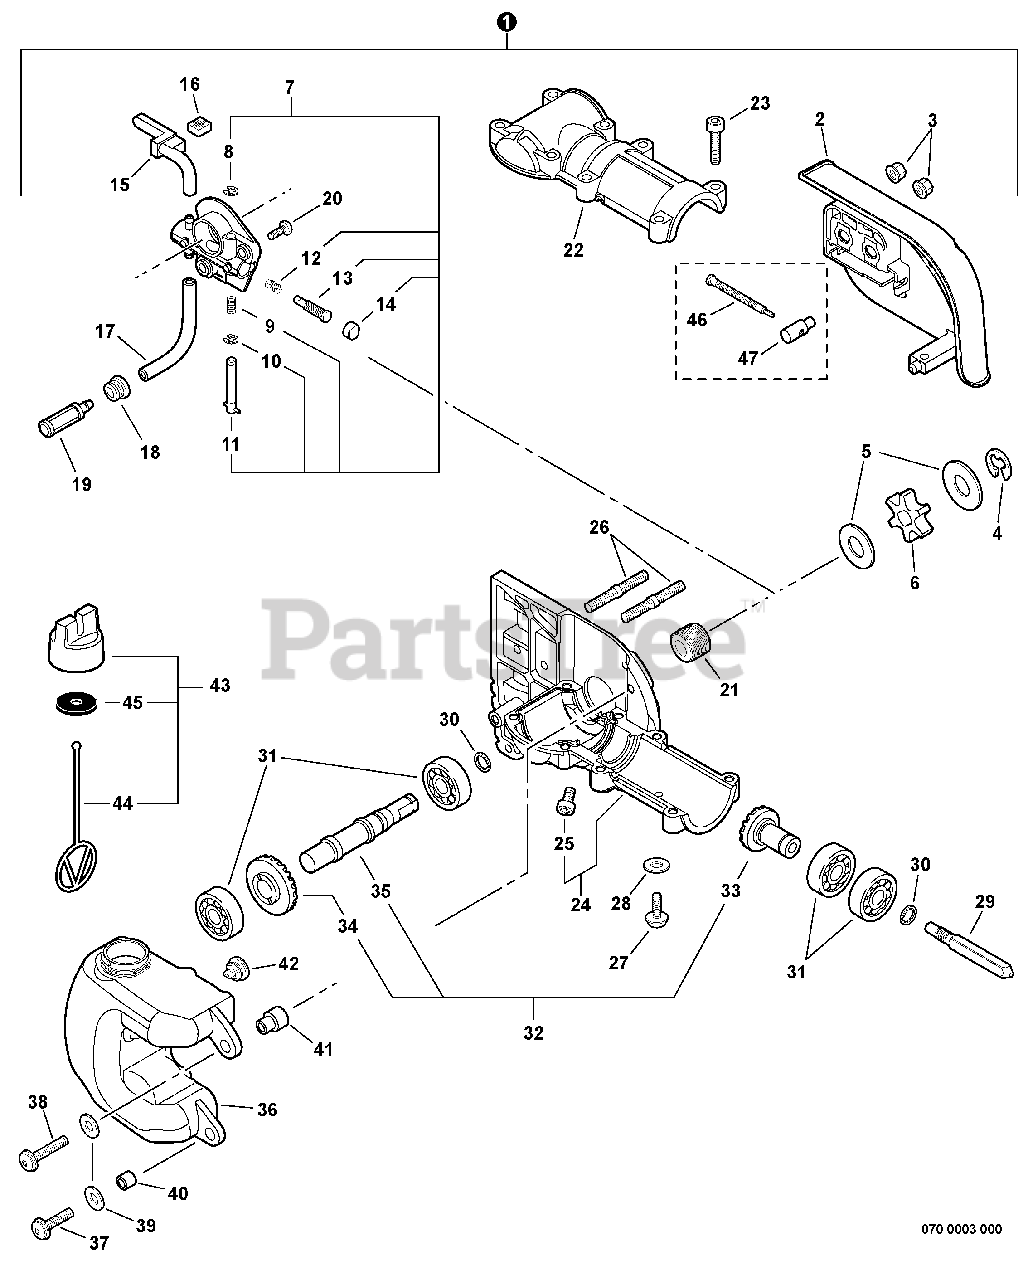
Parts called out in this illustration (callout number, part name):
1	CASE ASSY, OILER/GEAR
2	GUARD, SPROCKET
3	NUT, FLANGE M6
4	RING, RETAINING Ø0.300
5	WASHER 10.2×24.5×1.2
6	SPROCKET, DRIVE
7	AUTO-OILER ASSY
11	ADJUSTER, OILER
13	PLUNGER ASSY
14	CAP, OIL PUMP
15	PIPE, OIL OUTLET
16	PAD, FOAM
17	PIPE, IMPULSE 3×6×75
18	GROMMET
19	FILTER, OIL
20	BOLT 5×10
21	GEAR, WORM
22	CASE, GEAR - UPPER Ø35
23	BOLT 5×0.8×25
24	CASE ASSY, LOWER GEAR
25	BOLT 5×10
26	BOLT, STUD 6
27	BOLT 5×10
28	WASHER, FLAT 5.5×10×0.8
29	CONNECTOR, DRIVE SHAFT
30	RING, SNAP Ø12
31	BEARING, BALL
32	SHAFT KIT, GEAR
33	GEAR, BEVEL - 15 TOOTH
34	GEAR, BEVEL - 23 TOOTH
35	SHAFT, GEAR
36	TANK, OIL
37	BOLT 5×16
38	BOLT 5×0.8×25
39	WASHER 5.5×12×0.8
40	SPACER 6.2×7.8×6
41	COLLAR 6
42	VENT ASSY
43	CAP ASSY, OIL
44	CONNECTOR, CAP L= 60 MM
45	GASKET, CAP
46	BOLT 5
47	TENSIONER, CHAIN
